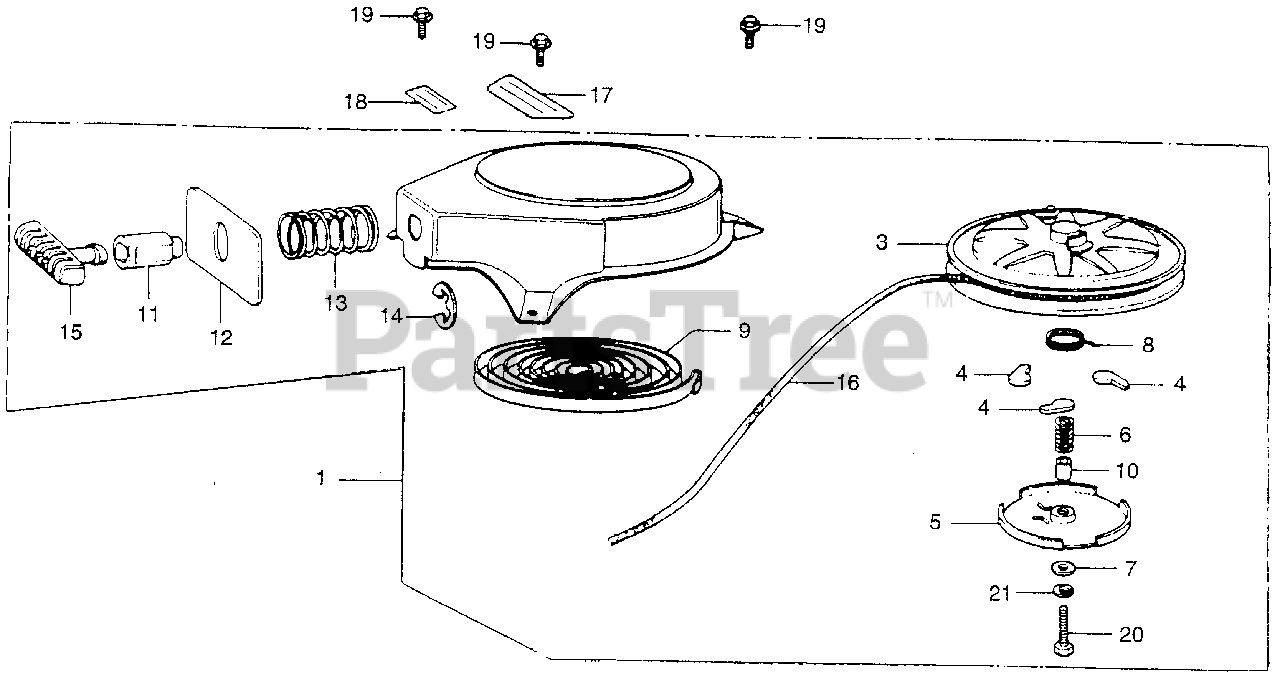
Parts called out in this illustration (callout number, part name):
1	STARTER ASSY., RECOIL
3	PULLEY, RECOIL STARTER
4	RATCHET, STARTER
5	PLATE, FRICTION
6	SPRING, FRICTION
8	SPRING SET
9	SPRING, RECOIL STARTER
11	GUIDE, ROPE
12	PLATE, SEAL
13	SPRING, SEAL PLATE
15	GRIP, STARTER
16	ROPE, RECOIL STARTER (#4X65") (NA USE ALT:08540-ZG921-11)
17	MARK, RECOIL STARTER CAUTION
18	LABEL, COMPLIANCE
19	BOLT, FLANGE (6X12)
20	BOLT, HEX. (6X25)
